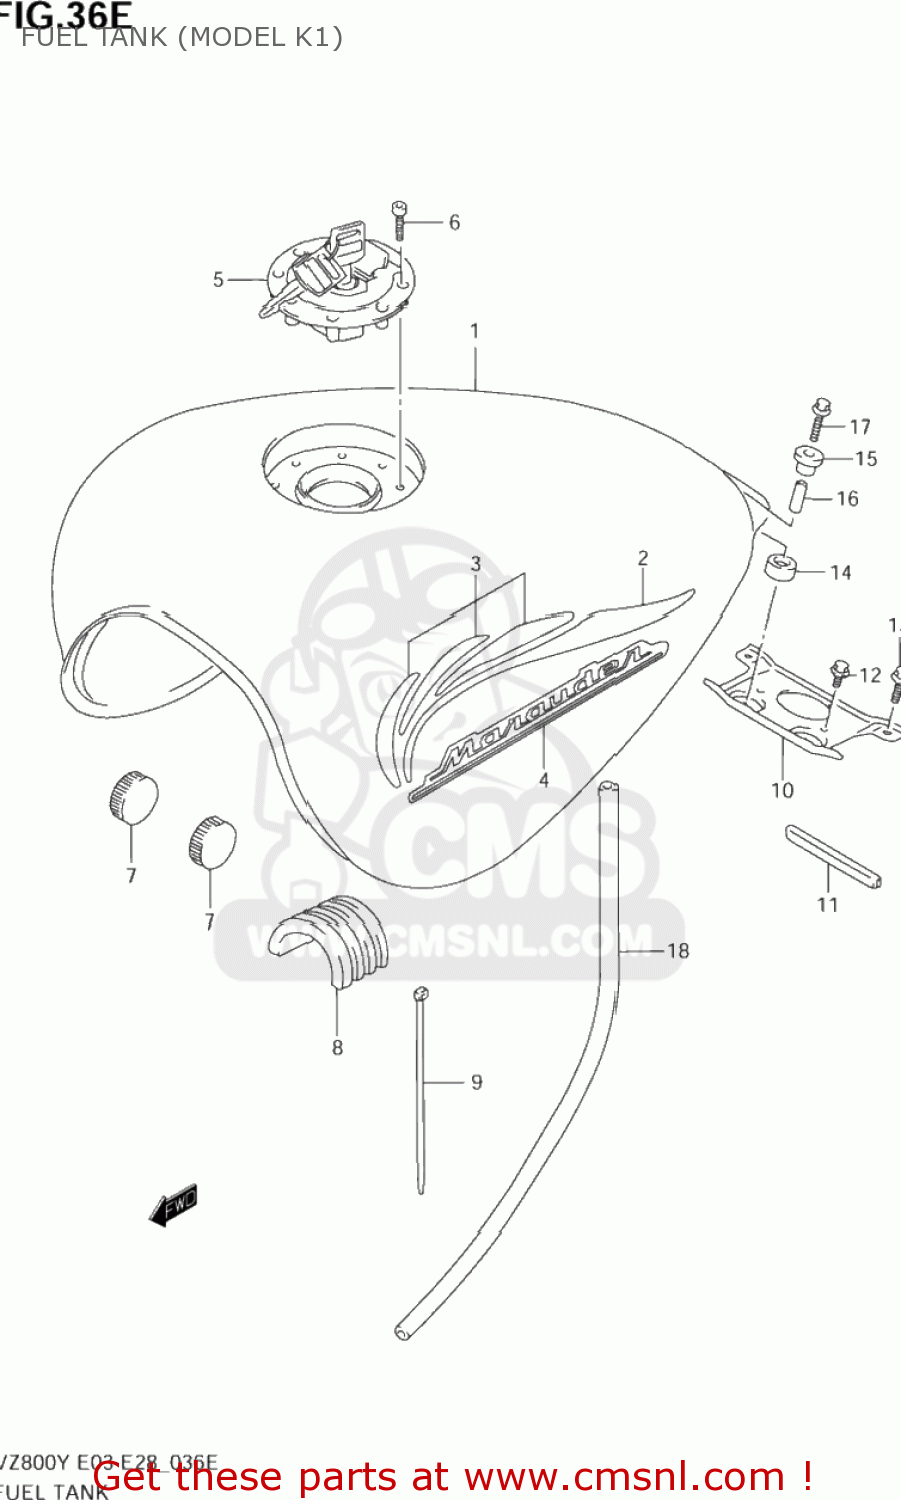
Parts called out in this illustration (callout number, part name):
1	TANK SET,FUEL(MAROON)
2	TAPE SET,FUEL TANK(SILVER)
3	EMBLEM SET,FUEL TANK
4	EMBLEM
5	CAP SET,FUEL TANK
6	BOLT(5X20)
7	CUSHION
8	CUSHION,FUEL TANK UPR
9	CLAMP(L:250)
10	BRACKET,FUEL TANK RR
11	PROTECTOR
12	BOLT
13	BOLT
14	CUSHION,FUEL TANK RR NO.2
15	CUSHION
16	SPACER(6.5X10.5X22.5)
17	BOLT
18	HOSE,FUEL TANK DRAIN
